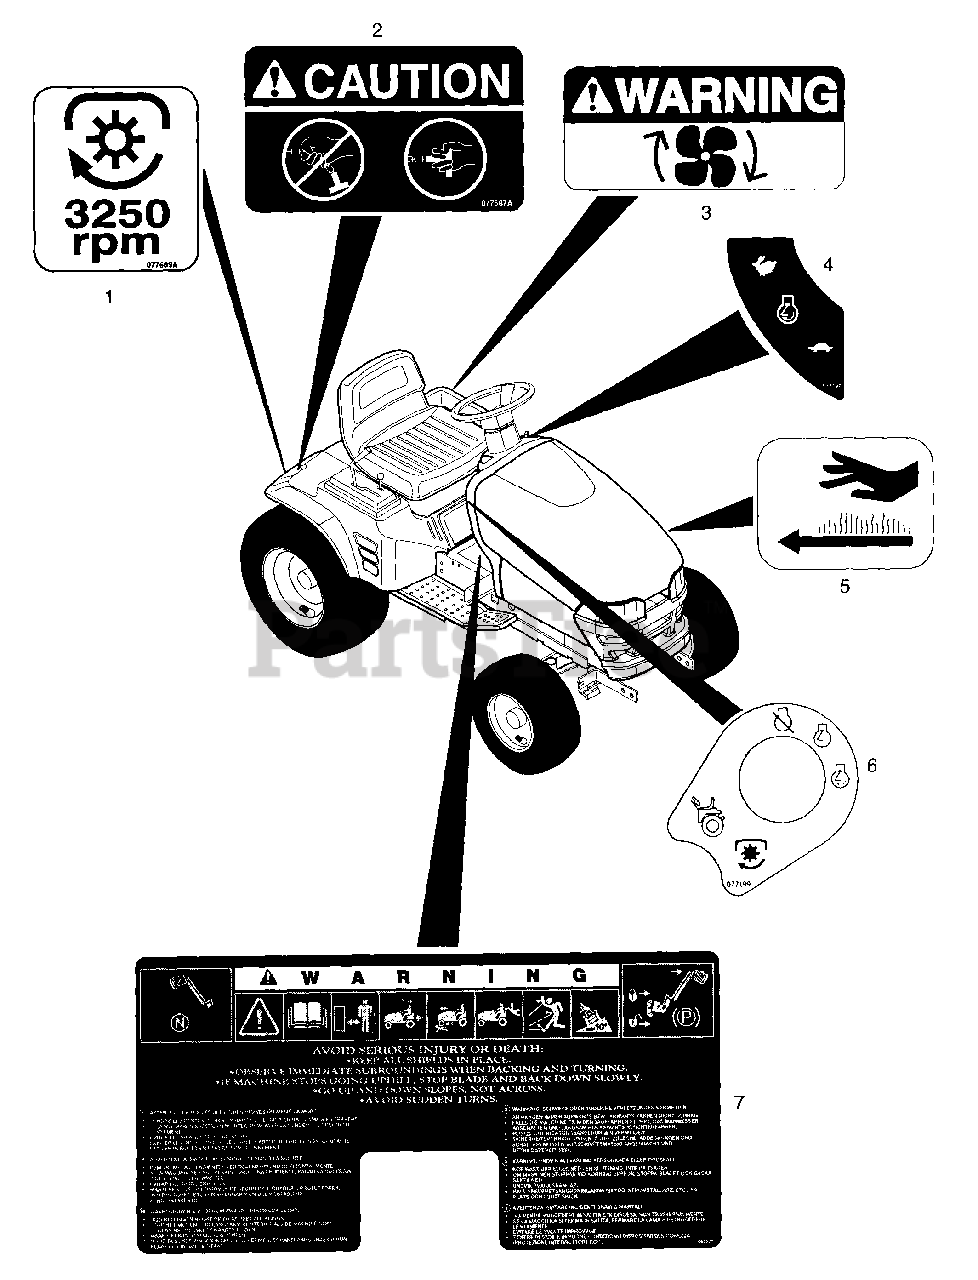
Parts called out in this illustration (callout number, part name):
1	Decal-PTO Speed
2	Decal-Caution
3	Decal-Warning-Fan
4	Decal-Throttle w/o Choke
5	Decal-Hot Surface
6	Decal-Ignition/PTO
7	Decal-Warning-Instruction
